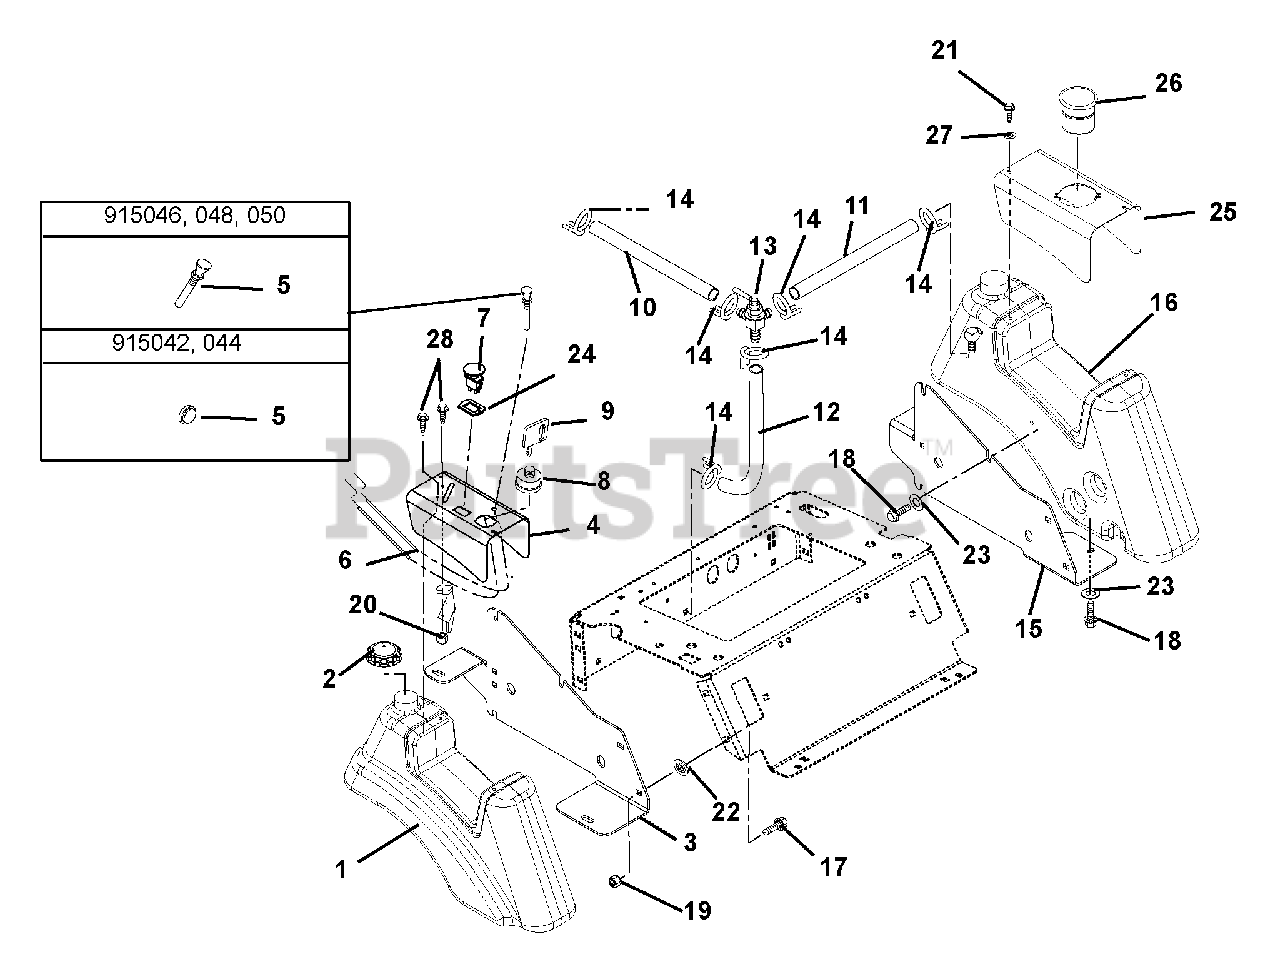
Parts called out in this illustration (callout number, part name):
1	Tank, Fuel - Right Hand
2	Fuel Cap
3	Seat Plate Right Hand
4	Right Hand Console
5	Choke Cable (046, 048, 050)
5	Hole Plug, Plastic .44 Hole (042, 044)
6	Throttle Cable (046, 048, 050)
6	Throttle Cable (042, 044)
7	Switch, Clutch
8	Key Switch
9	Key with Cap
10	Gas Line, Bulk .25 I.D. x 38 in. Long
11	Gas Line, Bulk .25 I.D. x 27 in. Long
12	Gas Line, Bulk .25 I.D. x 17 in. Long
13	Valve, Fuel
14	Clamp, Hose Wire .490/.510 x .116
15	Seat Plate Left Hand
16	Tank, Fuel - Left Hand
17	Bolt, Round Head Square Neck .38-16 x 1.00 Grade 5
18	Bolt, Serrated Hex Flange Washer Head .312-18 x .75
19	Nut .38-16 Flange Nyloc
20	Nut-Locking-Nylon 10-24 with Insert
21	Screw,Machine 10-24 x 3/8 Slotted Hex
22	Retainer .38 Push-On
23	Washer, Flat Steel .328 x 1.00 x .094
24	Shim, PTO Switch
25	Console, Left Hand
26	Cup Holder
27	Washer, Fender 3/16 x 3/4
28	Screw-Machine 10-24 x .50 Hex Washer Head
